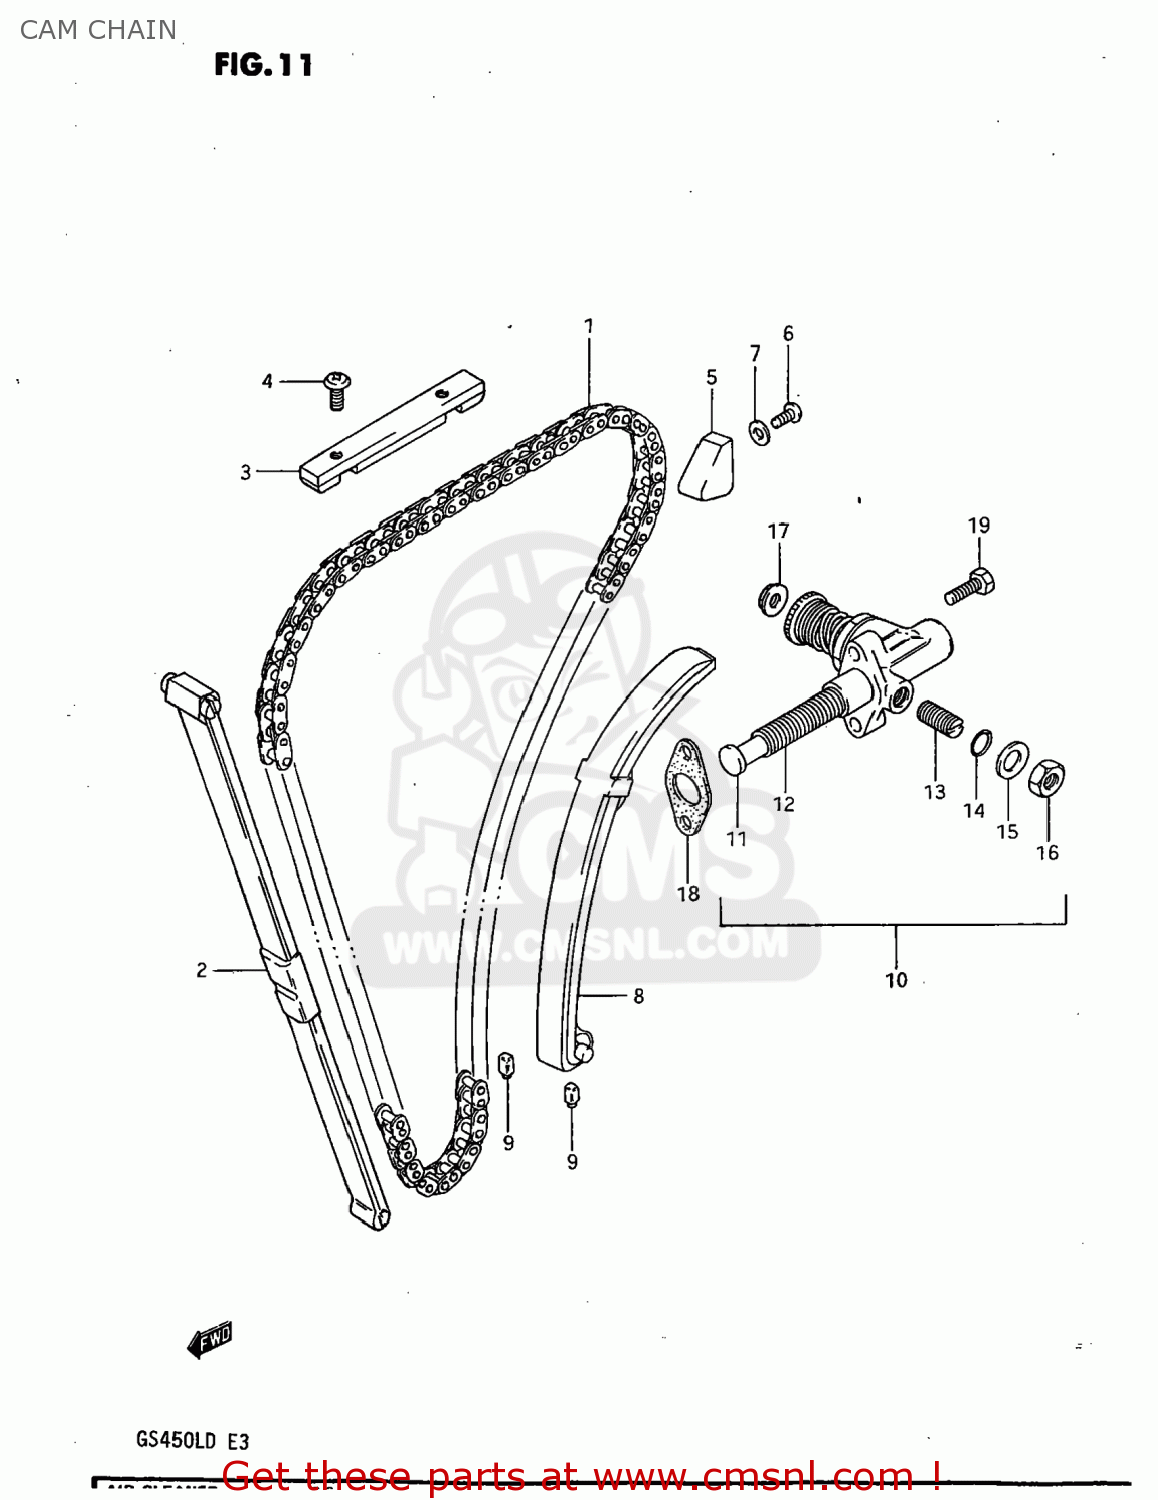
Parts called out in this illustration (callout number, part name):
1	CHAIN,CAMSHAFT DRIVE(120L)
2	GUIDE,CAM CHAIN NO.1
3	GUIDE,CAM CHAIN NO.3
4	SCREW
5	GUIDE,CAM CHAIN
6	BOLT
7	GASKET (NAS)
8	TENSIONER,CAM CHAIN
9	CUSHION,CAM CHAIN TENSIONER
10	ADJUSTER ASSEMBLY,TENSIONER
11	ROD,PUSH
12	SPRING
13	SCREW
14	O-RING
15	WASHER
16	NUT
17	NUT
18	GASKET,TENSIONER ADJUSTER (MCA)
19	SCREW (6X25)
